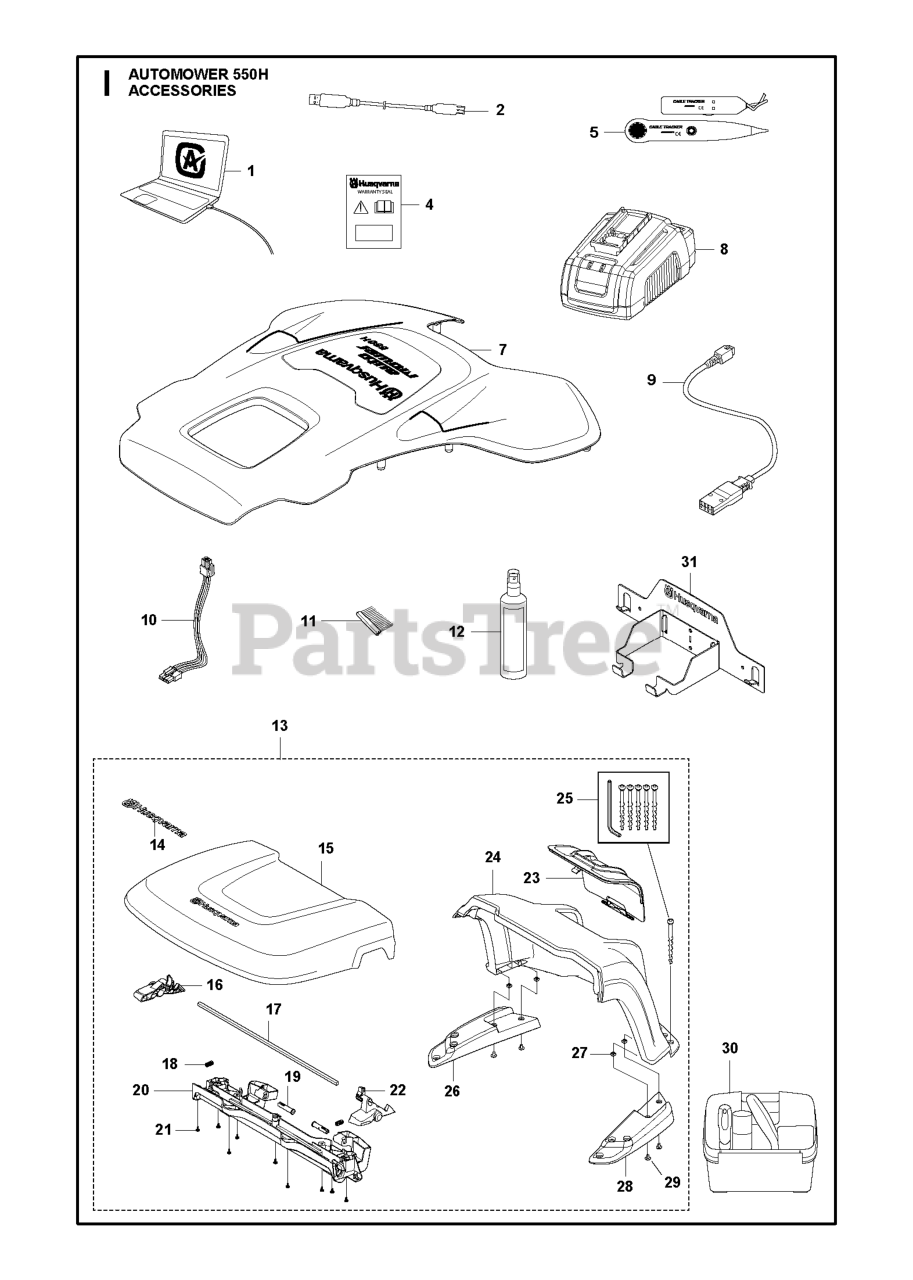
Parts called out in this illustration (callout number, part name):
2	CABLE WHITE ALT GREY
4	LABEL WARRANTY SEAL DEALER
5	TEST EQUIPMENT
7	Body
7	BODY KIT SPARE PART TOP COVER
8	CHARGER BATTERY TEST
9	CABLE ASSY QUICK CHARGER
10	WIRING ASSY BATTERY CABLE
11	WHEEL BRUSH REFILL KIT
12	AUTOMOWER ACCY
13	COVER
14	DECAL
16	HANDLE RELEASE LEFT
17	ROD
18	SPRING SPRING CAP
19	HINGE PIN
20	BEAM
21	SCREW 14MM
22	HANDLE RELEASE RIGHT
23	HATCH
25	Screws
26	SUPPORT BASE LEFT
27	NUT
28	SUPPORT BASE RIGHT
29	SCREW IHPANM M6X25 4.6 ZP-BC
30	CLEANING AND MAITENANCE KIT AM
31	HANGER
